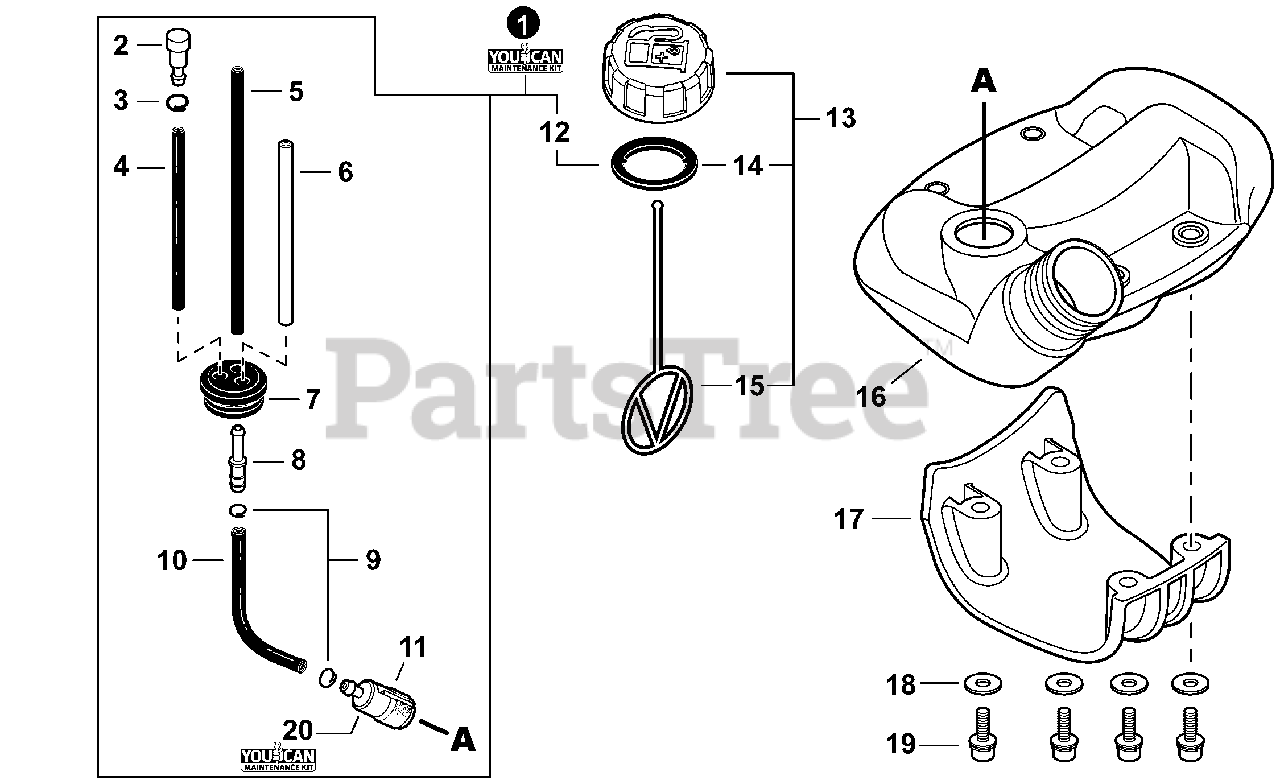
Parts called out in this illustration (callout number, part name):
1	FUEL SYSTEM KIT - YOUCAN™
2	VENT ASSY
3	CLIP 6.5MM
4	PIPE, FUEL 3×6×35 BLACK
5	PIPE, FUEL - 3×5×67 - BLACK
6	PIPE, FUEL 3×6×75 CLEAR
7	GROMMET, FUEL
8	CONNECTOR, PIPE 5×3.5
10	PIPE, FUEL - 3×5×125 - BLACK
11	FILTER, FUEL
12	GASKET, FUEL CAP
13	CAP ASSY, FUEL
14	GASKET, FUEL CAP
15	CONNECTOR, CAP L= 100mm
16	TANK, FUEL
17	GUARD, FUEL TANK
18	WASHER 5.5×12×0.8
19	BOLT 5×25
20	TUNE-UP KIT - YOUCAN™
